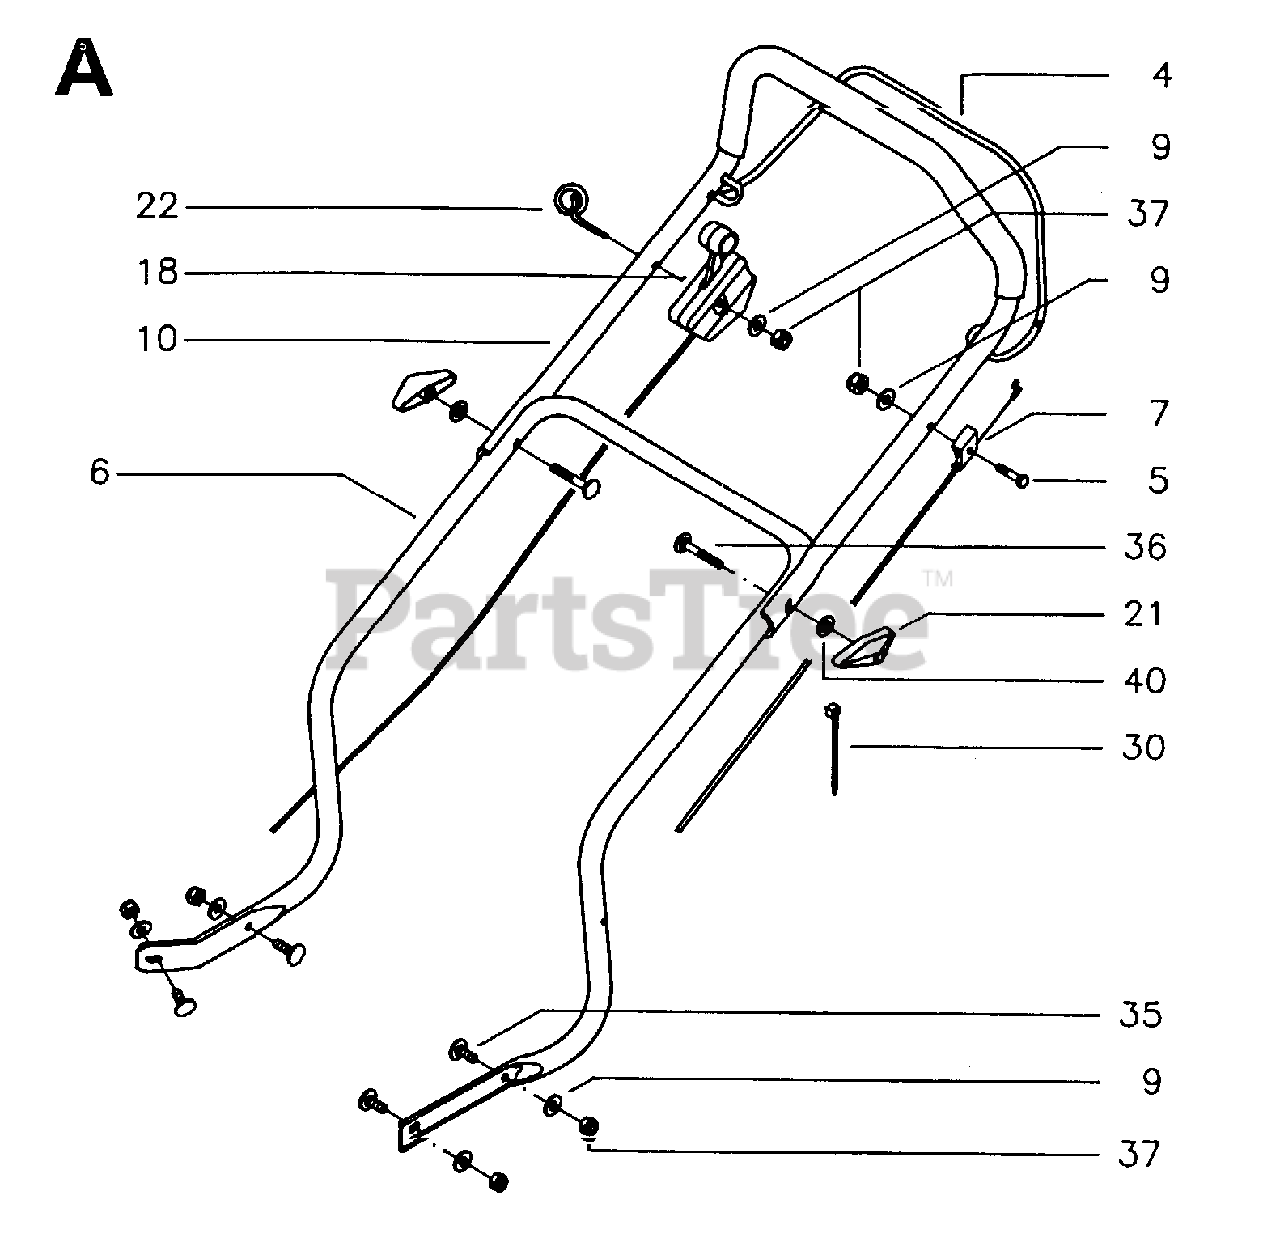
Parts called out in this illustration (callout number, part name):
5	BOLT FLANGE
18	CONTROL
37	LOCKNUT M6
40	WASHER - 15X7.3X1.6
